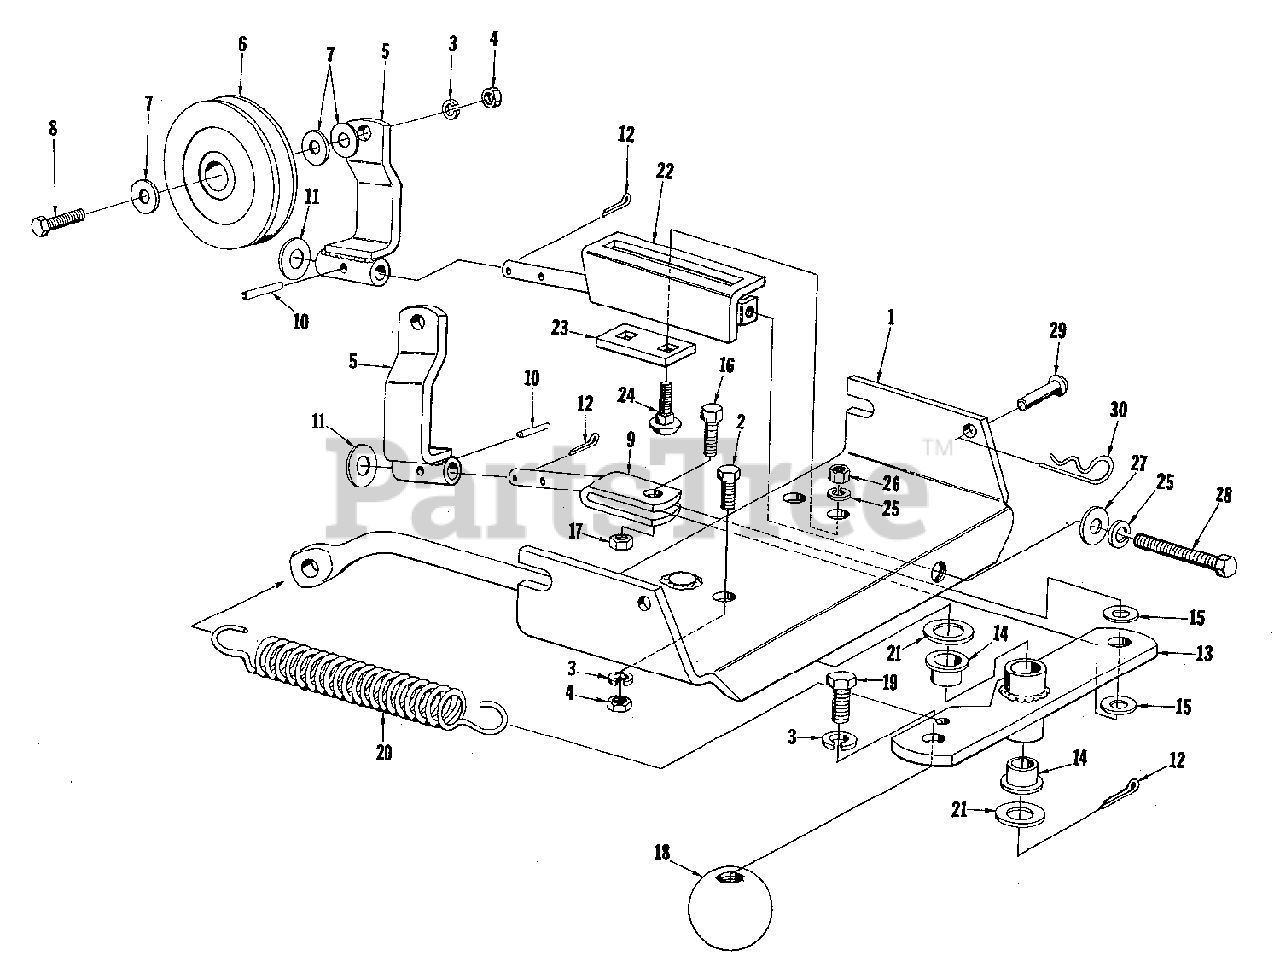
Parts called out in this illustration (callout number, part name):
1	SUPPORT ASSEMBLY
2	SCREW, Hex Head Cap, 3/8-16 x 1-1/4
3	WASHER, Lock, 3/8"
4	NUT, Hex, 3/8-16
5	BRACKET ASSEMBLY, Idler
6	PULLEY, Idler
7	WASHER, Flat
8	SCREW, Hex Head Cap, 3/8-16 x 1-1/2
9	CLEVIS ASSEMBLY
11	WASHER, Flat
13	ARM ASSEMBLY, Pivot
14	BEARING, Nylon
15	WASHER, Nylon
16	SCREW, Special, Cap
17	NUT, Hex Lock, 3/8-16
19	SCREW, Hex Head Cap, 3/8-16 x 7/8
20	SPRING, Extension
21	WASHER, Flat
22	BRACKET ASSEMBLY
23	PLATE, Reinforcement
24	BOLT, Carriage, 5/16-18 x 1
25	WASHER, Lock, 5/16
26	NUT, Hex, 5/16-18
27	WASHER, Flat
28	SCREW, Hex Head Cap, 5/16-18 x 2-1/2
29	PIN, Round Head
